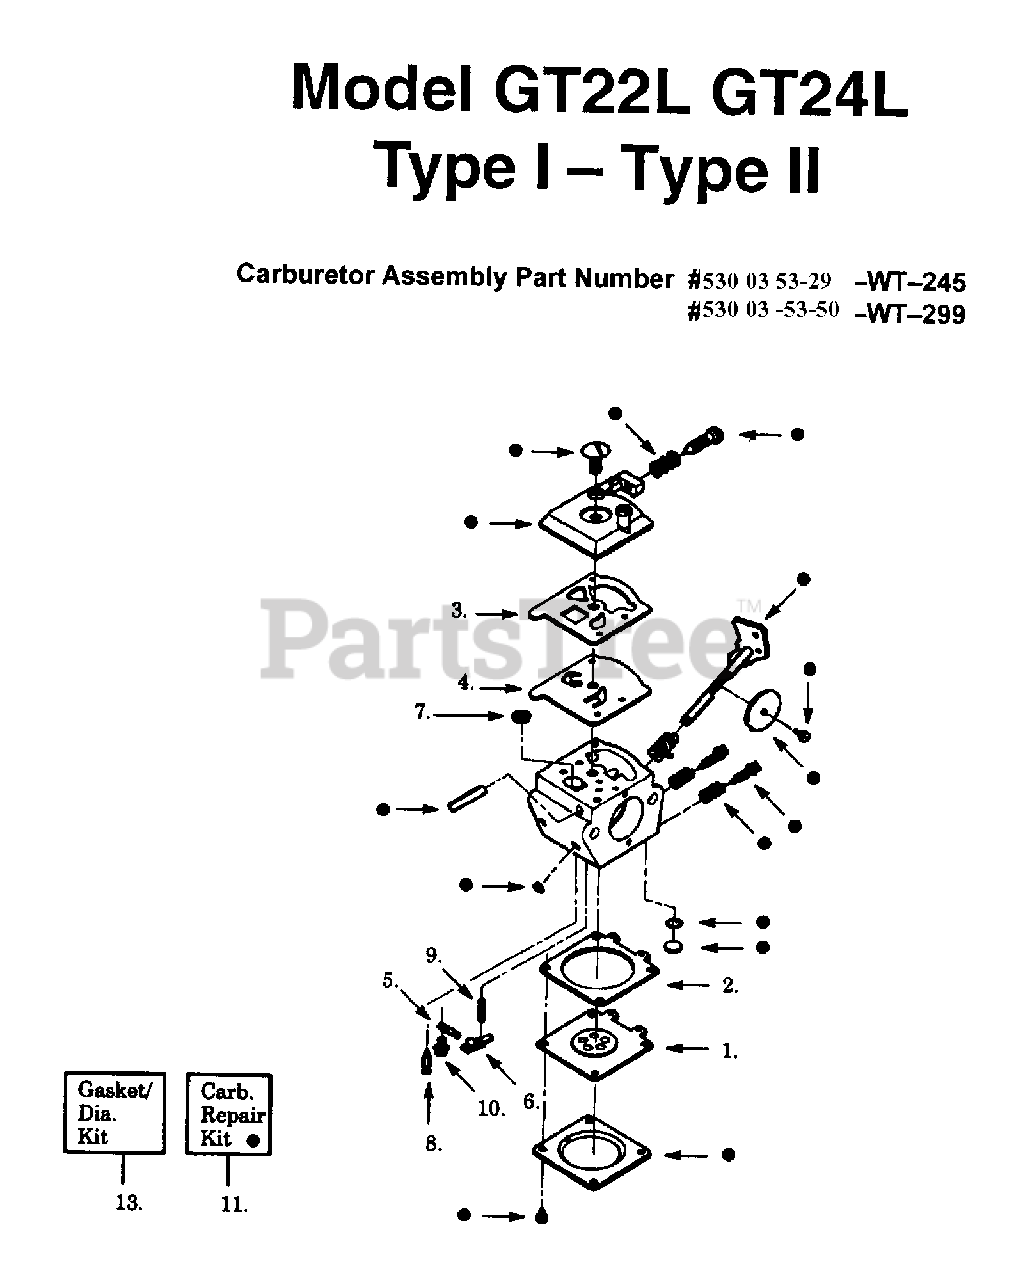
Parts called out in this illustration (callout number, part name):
1	METERING DIAPHRAGM
2	GASKET-METERING DIAPHRAGM
4	PUMP DIAPHRAGM
5	FULCRUM PIN
7	SCREEN-DUTCH TWILL INLE
8	VALVE/INLET.
9	METERING LEVER SPRING
11	CARBURETOR REPAIR KIT
